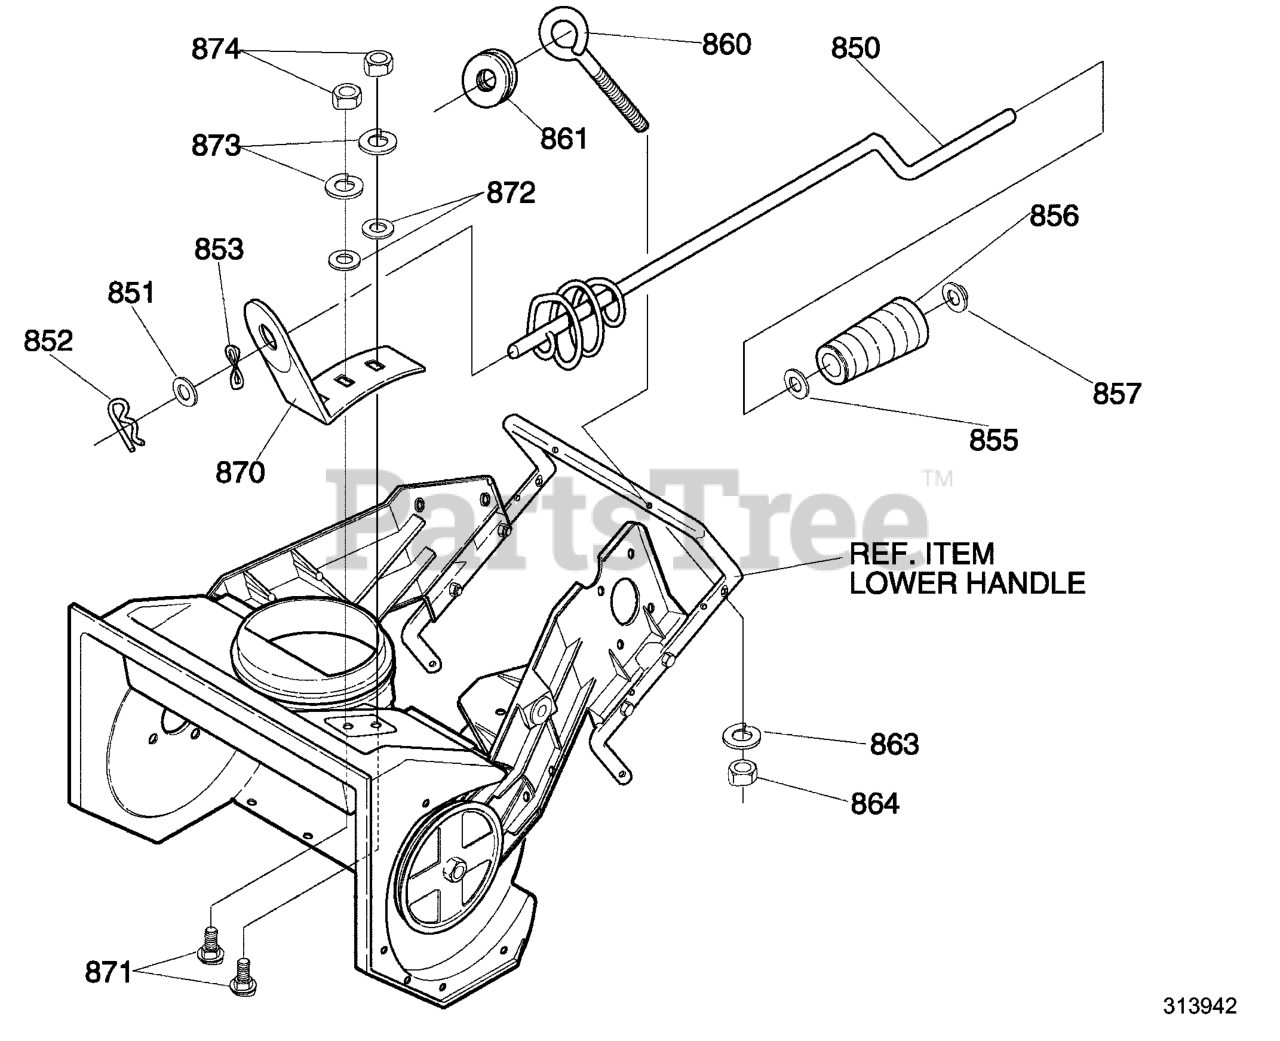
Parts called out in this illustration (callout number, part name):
850	ROD, ASSY UPPER CHUTE CONTROL
851	WASHER, FLAT .406X.81X.066
852	PIN, COTTER
853	WASHER, CURVED SPRING
855	WASHER, FLAT .406X.81X.066
856	KNOB, SLEEVE
857	NUT, PUSH
860	BOLT, EYE 3/8-16X2.00
861	GROMMET, EYE BOLT
863	WASHER
864	NUT, HEX JAM 3/8-16
870	BRACKET, CHUTE ROTATE
871	BOLT, CARRIAGE 5/16-18X.75
872	WASHER, FLAT .349X.69X.066
873	WASHER .328X.60X.09
874	NUT, HEX 5/16-18
